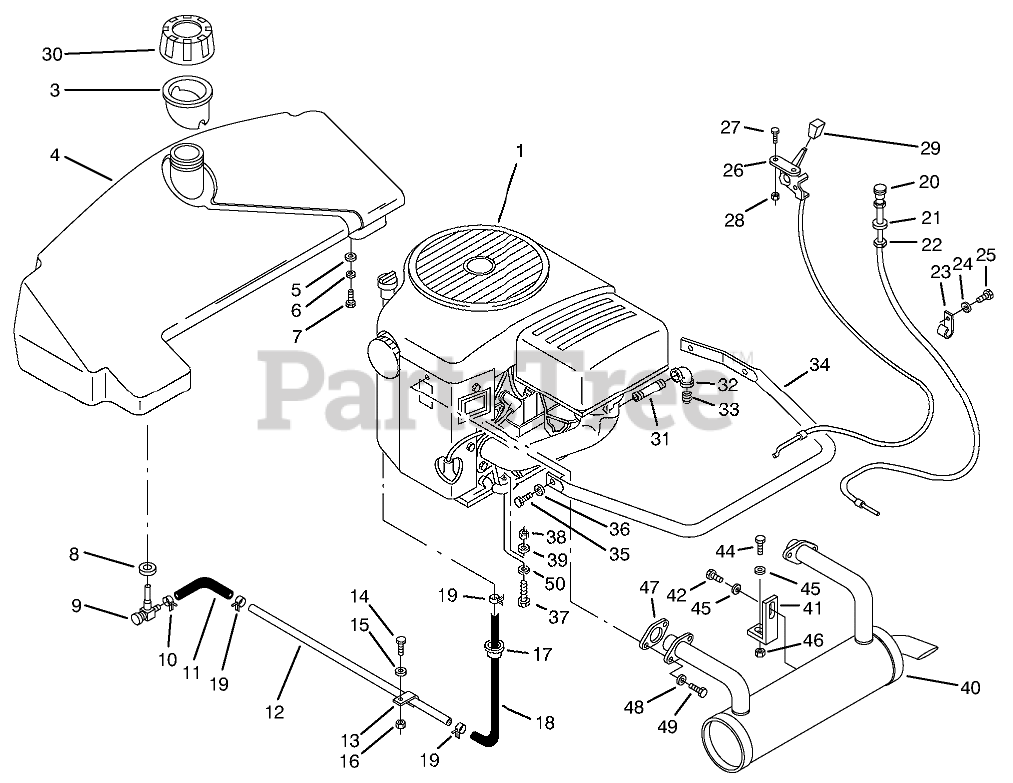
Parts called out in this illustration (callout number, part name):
1	Engine-16HP Model P216V-1/11103-D
3	FUNNEL-FUEL TANK
4	TANK-FUEL ASS'Y
5	Collar
6	Lockwasher
7	Bolt
8	BUSHING
9	VALVE-FUEL
10	CLAMP-HOSE
11	HOSE-FUEL
12	TUBE FUEL LINE
13	J-CLIP
14	Bolt
15	WASHER-PLAIN
16	NUT-LOCK, NI
17	BUSHING-NYLON 1.093
18	Hose-18" Fuel
19	CLAMP HOSE .5 IN
20	CONTROL-CHOKE
21	WASHER-FLAT
22	NUT-HEX PALNUT
23	CLIP
24	Washer
25	Bolt
26	CONTROL-THROTTLE
27	SCREW-PPH
28	NUT-LOCK, NI
29	KNOB-CONTROL
30	GAS CAP ASM
31	NIPPLE-3/8 X 2.5
32	ELBOW 3/8 90 DEG
33	Plug
34	GUARD-AIR CLEANER
35	WASHER-FLAT
36	Washer
37	Bolt
38	NUT-LOCK, NI
39	WASHER-PLAIN
40	EXHAUST-MUFFLER
41	BRACKET-MUFFLER
42	SCREW-HH
43	WASHER-PLAIN
44	SCREW-HH
45	WASHER-PLAIN
46	NUT-LOCK, NI
47	GASKET
48	Lockwasher
49	SCREW-HSH
50	WASHER
